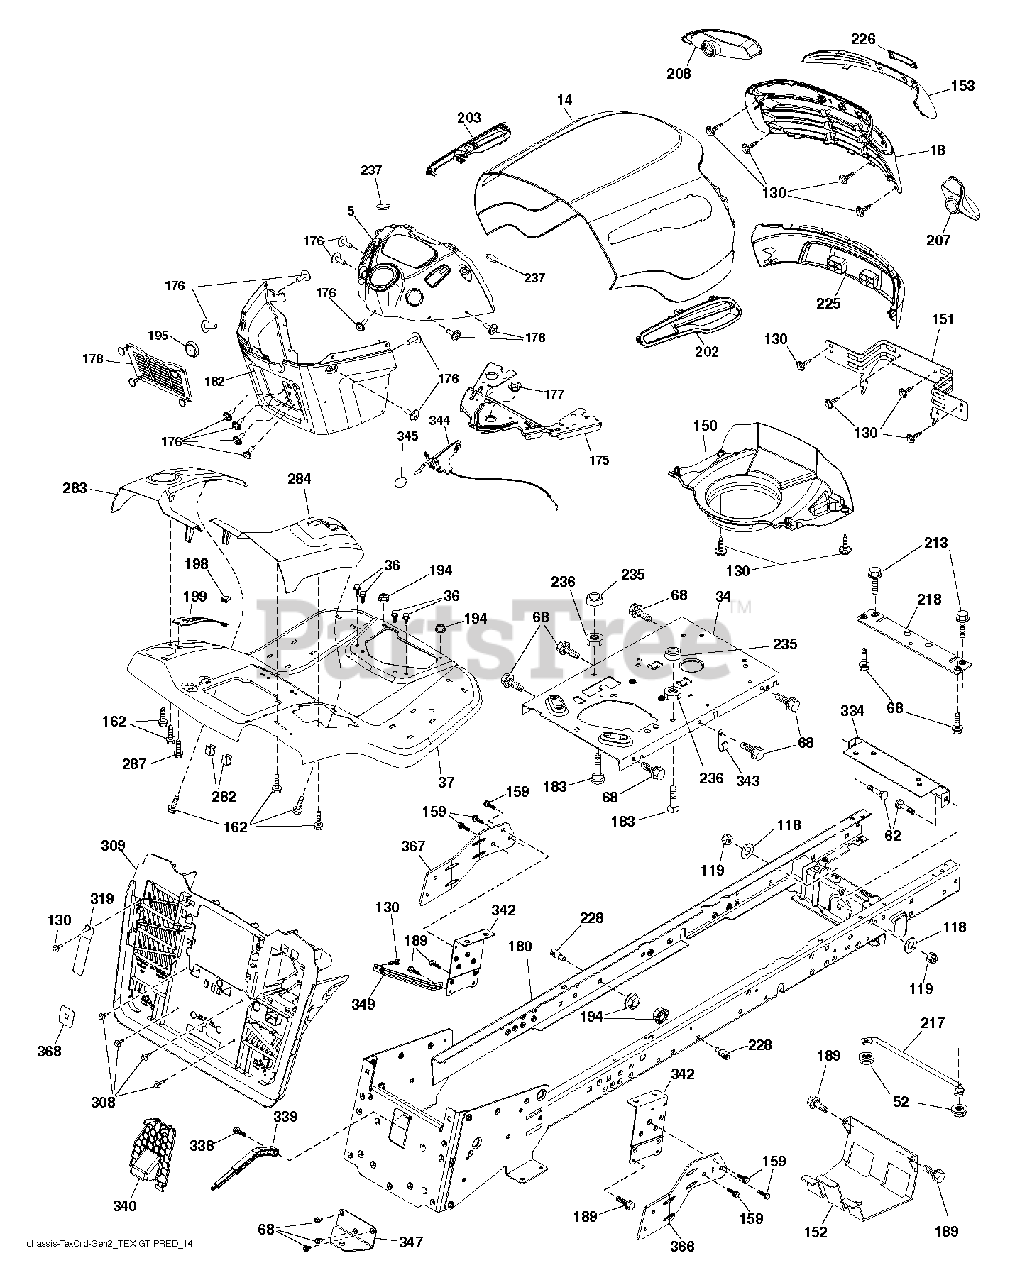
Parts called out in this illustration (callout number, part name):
36	SCREW 5/16"
52	LOCKNUT
119	LOCKNUT
130	SCREW.#10 X 0.750.BOS THREAD
150	PREDATOR.YT.GT.HOOD.A
152	SHIELD BROWNING
159	SCREW, 3/8-16X3/4
162	SCREW.HI-LO.CONSOLE
175	PLATE.CROSSMEMBER.HUSQ
176	SCREW.#10-24X5/8.RN.QU
177	BUSHING,STEERING
178	CARGO.ASM.NET.TXGT.W/C
180	WELDMENT.CHASSIS.TEX.
183	BOLT.5/16-18X1-1/4 FULL THD
189	SCREW
194	NUT LOCK HEX FLANGE 5/16-18
195	PLUG.HOLE.DASH.LOWER.12V.BLK
198	INDICATOR.DECK.LIFT.RED
213	BOLT
217	ROD.PIVOT.HOOD
218	X-PIECE.HOOD.STOP.NON/
228	STUD.FASTNER.W/ANTI-ROTATE
235	SPACER FENDER
236	NUT.CENTERLOCK.5/16-
237	PLUG.MOUNT.CARGO.BLK
282	CLIP.RETAINER.CONSOLE.LT.HUSQ
308	BOLT, 5/16-18 X 1 3/4
309	BACKPLATE.ASM.CRDII.A
